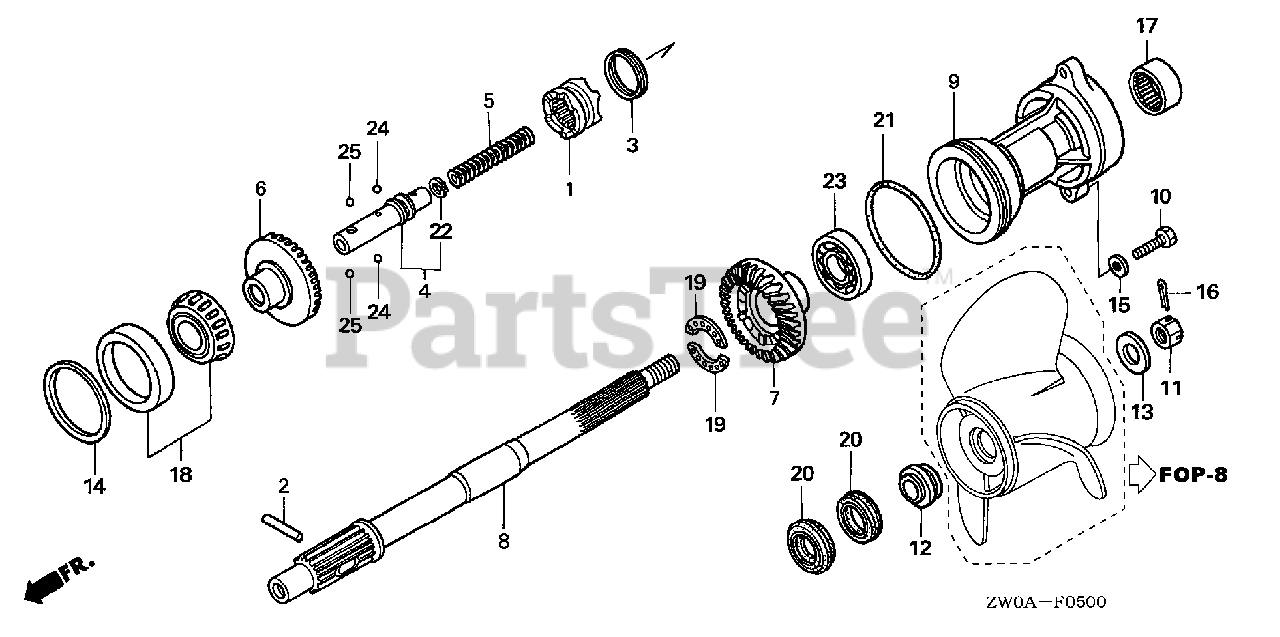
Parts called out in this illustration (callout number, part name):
1	SHIFTER, CLUTCH
2	PIN, SHIFTER (8X47)
3	RING, CROSS PIN
4	SLIDER, SHIFT
5	SPRING, SHIFT
6	GEAR, BEVEL (F)
7	GEAR, BEVEL (R)
8	SHAFT, PROPELLER
9	HOLDER, PROPELLER SHAFT *NH282MU* (OYSTER SILVER METALLIC-U)
10	BOLT, HEX. (10X40)
11	NUT, CASTLE (18MM)
12	WASHER, PROPELLER THRUST
13	WASHER, PLAIN (18.5MM)
14	SHIM A, BEVEL (0.10) (FR)
14	SHIM B, BEVEL (0.15) (FR)
14	SHIM C, BEVEL (0.30) (FR)
14	SHIM D, BEVEL (0.50) (FR)
15	WASHER, PLAIN (10MM)
16	PIN, SPLIT (4.0)
17	BEARING, NEEDLE (30X37X26)
18	BEARING, TAPERED ROLLER (50X82X21.5)
19	BEARING, BALL (28X38X3)
20	SEAL, WATER (30X45X7)
21	O-RING (94X4.1)
22	CIRCLIP (OUTER) (14MM)
23	BEARING, RADIAL BALL (6208)
24	BALL, STEEL (#6) (3/16)
25	BALL, STEEL (#11) (11/32)
